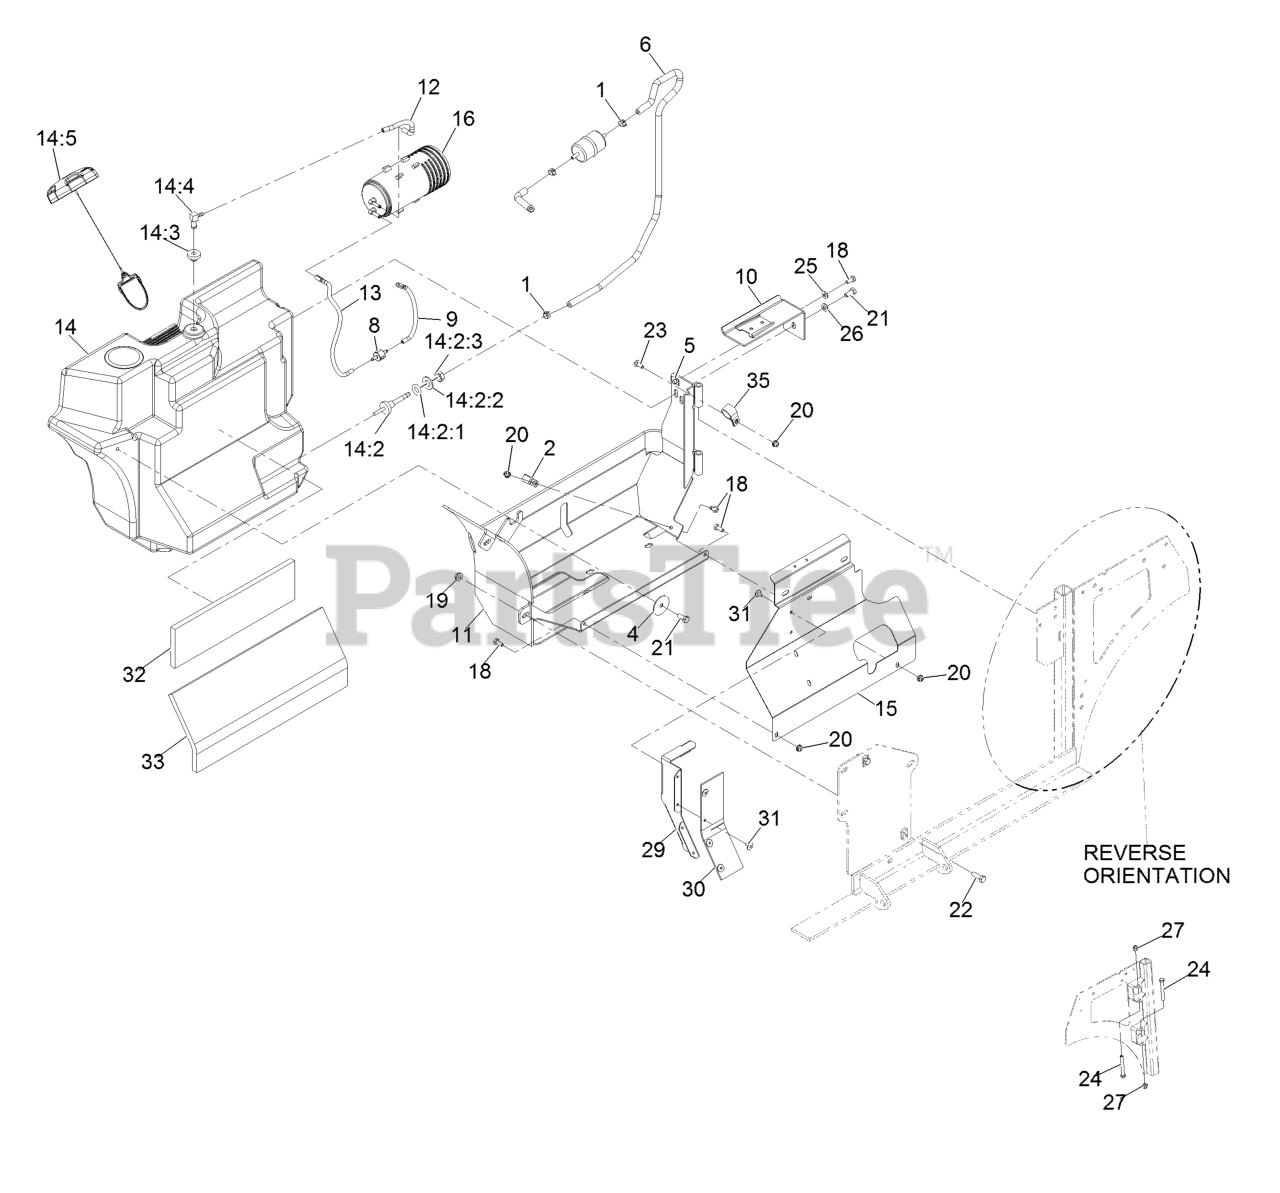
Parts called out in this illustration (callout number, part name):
1	Clamp-Hose
2	Clip-Loom 1/2
5	Nut-Retainer-Panel 1/4-20
6	Fuel Line ASM
8	Valve-Check, Vacuum
9	Hose-Vent, Formed
10	Canister Bracket ASM
11	Tank Frame ASM
12	Hose-Vent, Formed
13	Hose-Vent, Formed
14	Fuel Tank ASM
14:2	Fitting-Fuel Bulkhead W/Screen
14:2:2	Washer-1/2 SAE
14:2:3	Nut-Jam 1/2-20
14:3	Bushing
14:4	Fitting-90 DEG
14:5	Cap-Fuel, Ratcheting
15	Panel-Tank Shield
16	Canister-Carbon, 800Cc
18	Screw-HH 1/4-20 X 5/8
19	Nut-Whizlock 5/16-18
20	Nut-Nyloc 1/4-20 Flg
21	Screw-HH 5/16-18 X 3/4
22	Screw-HH 5/16-18 X 1
23	Bolt-Carriage 1/4-20 X 3/4
24	Screw-HH 3/8-16 X 3
25	Washer-1/4 SAE
26	Washer-5/16 SAE
27	Nut-Nyloc 3/8-16
29	Deflector-Air
30	Flap-Rubber
31	Rivet 3/16 X 1/4
32	Insulation-Foam Pad, Front
33	Insulation-Foam Pad, Rear
35	R-Clamp
